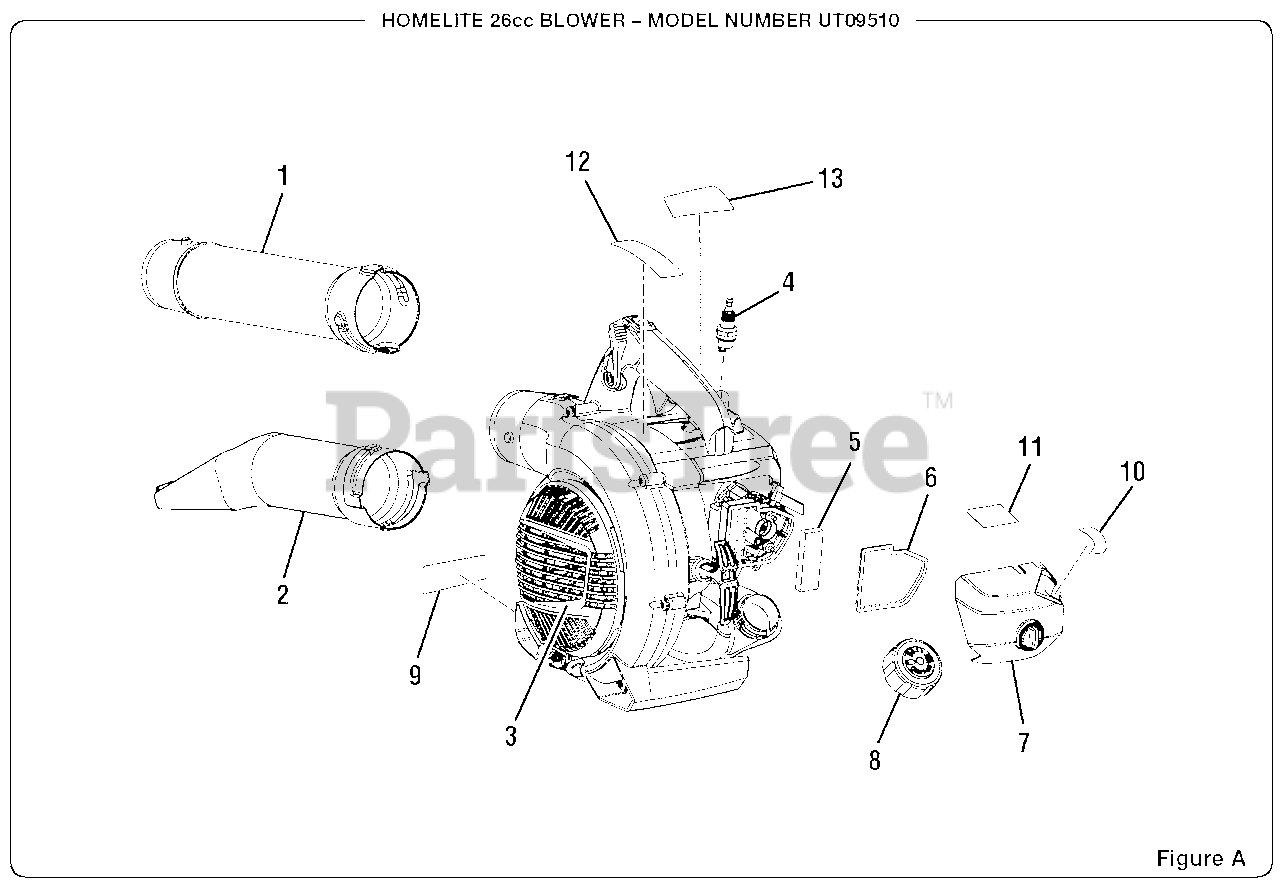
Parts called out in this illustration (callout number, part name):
1	Blower Tube
2	High Velocity Nozzle w/Leaf Scraper
3	Air Inlet Cover
4	Spark Plug (RCJ6Y)
6	Air Box Gasket
7	Air Filter Cover
8	Fuel Cap Assembly
9	Combustion Warning Label
10	Choke Label
11	Starting Label
12	Warning Label
13	Logo Label
